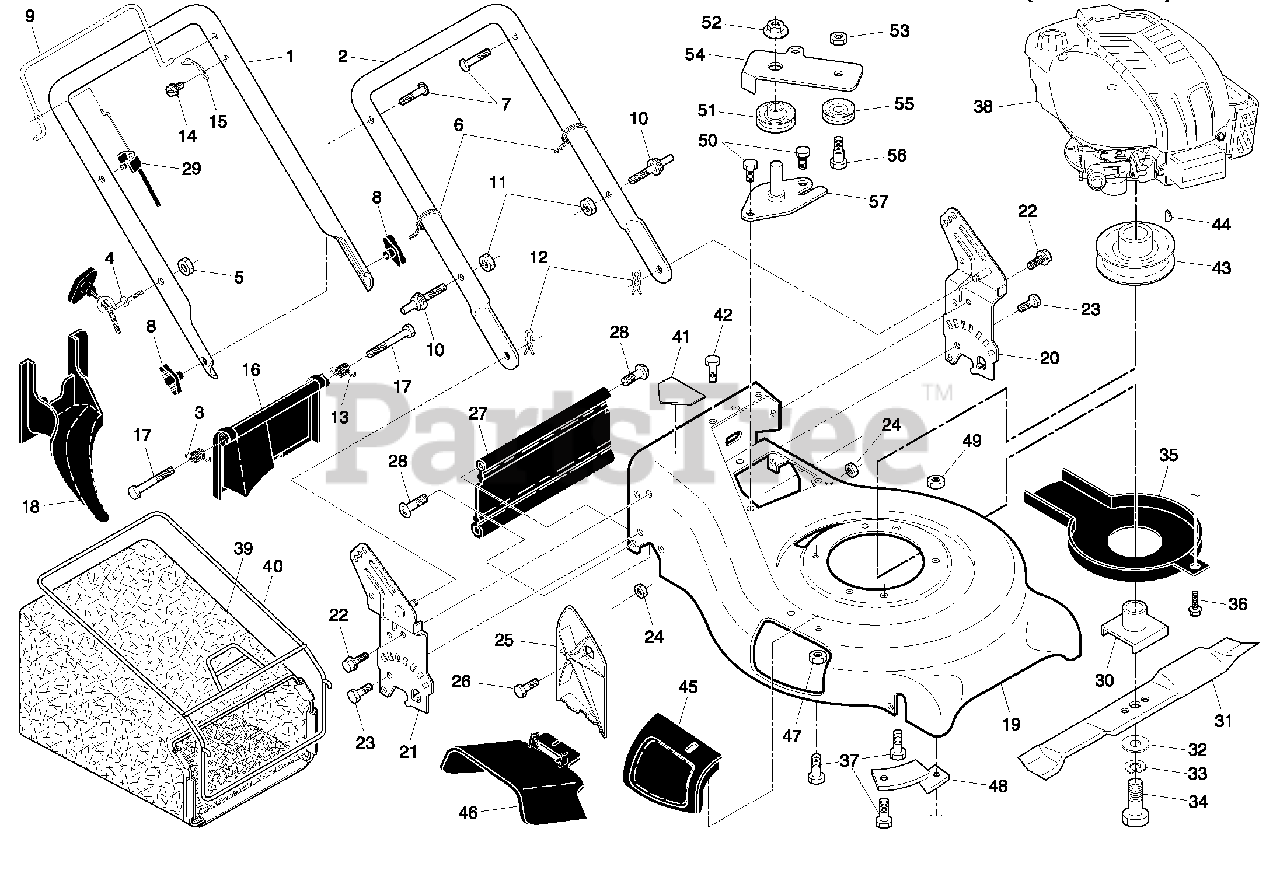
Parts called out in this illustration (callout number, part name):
1	Drive Control Assembly
2	Control Bar, Drive
3	Nut, Hex
4	Screw
5	Cover, Drive
6	Screw, Threaded, Rolled #10-25 x .50
7	V-Belt
8	Nut, Flangelock, Zinc Plated 3/8-16
9	Pulley, Drive
10	Pinion, Gear
11	Screw
12	Retainer, Drive, RH
13	Gear Case Assembly, Complete
14	Pin, Spring, Thrust
15	Washer, Hardened
16	Rod, Connecting
17	Spring, Extension
18	Spring, Selector
19	Knob, Selector Spring
20	E-Ring 7/8
21	Bearing, Support
22	Bearing, Ball
23	Retainer, Drive Assembly
24	Screw, Tapping, Hex Head 1/4-20 x .75
25	Pawl
26	Spring, Torsion
27	Washer, Shim (as required)
28	E-Ring 7/16
29	Cover, Dust, Wheel
30	Disc, Drive
31	Nut, Flangelock
32	Wheel, Rear, Self-Propelled 9 x 2
33	Nut, Flangelock 3/8-16
34	Hubcap, Mag, Platinum
35	Shaft Assembly, Rear
36	Shaft Assembly, Front
37	Retainer, Front Shaft
38	Screw #12 x 5/8
39	Clip, Retainer
40	Wheel, Front 8 x 2
41	Seal, Friction
42	Pinion / Pawl Assembly, RH
43	Washer
44	Pinion / Pawl Assembly, LH
45	Washer
46	Retainer, Drive, LH
50	Case, Lower
51	Case, Upper
52	Gear, 24 Teeth
53	Shaft, Input
54	Wire, Formed
55	Bearing, Ball
56	Seal, Output Shaft
57	Washer
58	Bushing
59	Shaft, Output
60	Screw
61	Seal, Input Shaft
